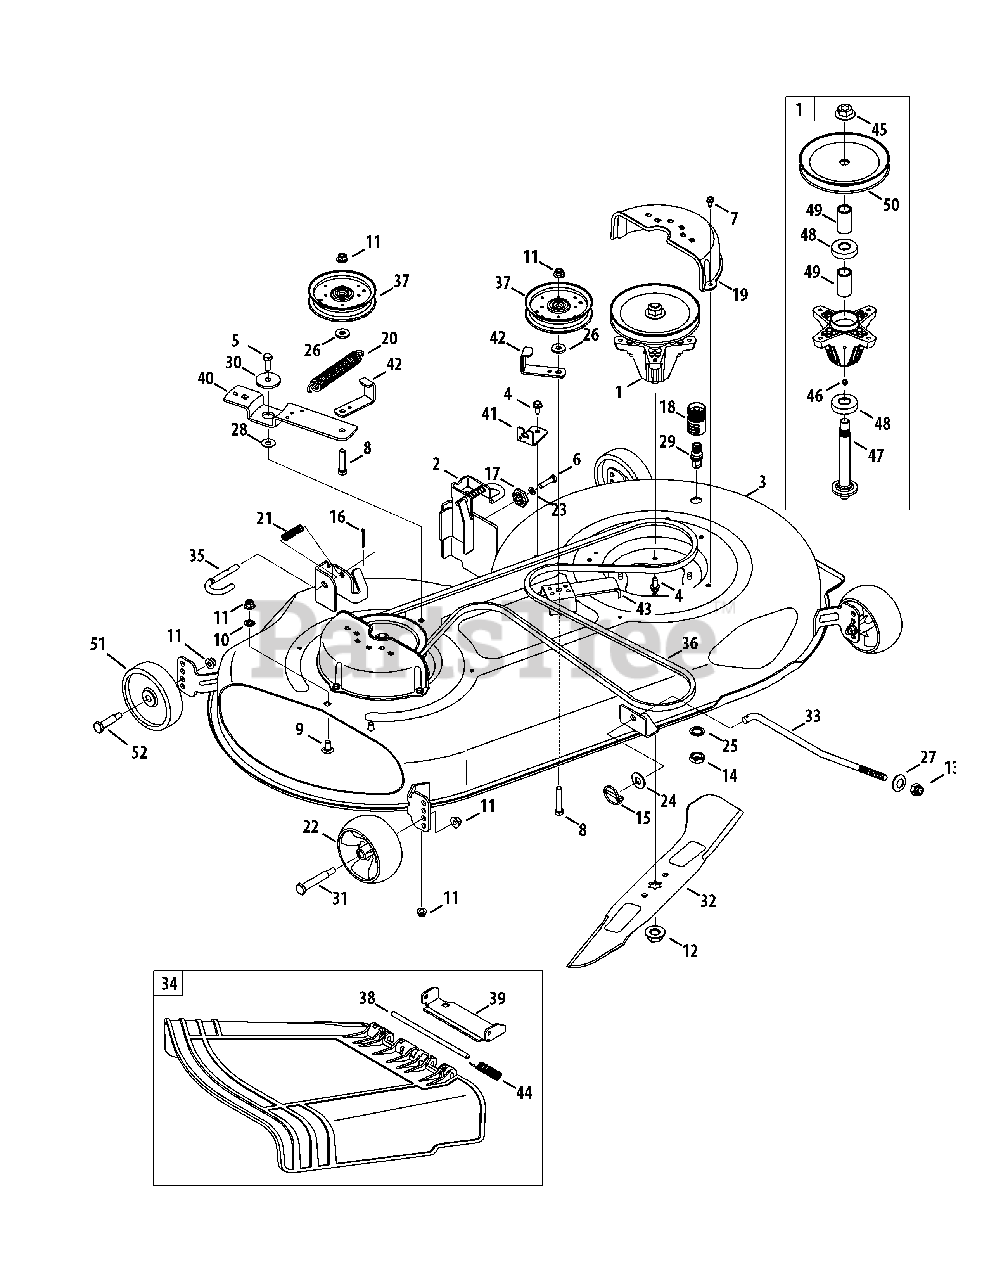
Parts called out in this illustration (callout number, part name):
1	Spindle Assembly, w/Pulley 6.93 Dia.
2	Bracket Assembly, Deck, Hanger LH
3	Deck Assembly, Offset, 46"
4	Screw, Self-tapping, 5/16-18, .750,
5	Hex Screw, 3/8-16, 1.00, Gr5, Std
6	Hex Screw, 5/16-18, 1.25, Gr5, Std
7	Screw, Self-tapping, 1/4-20, 0.500,
8	Hex Screw, 3/8-16, 2.00, Gr5, Std
9	Bolt, Carriage, 3/8-16, 0.75, Gr1
10	Nut, Push, 3/8
11	Nut, Flange Lock, 3/8-16, Nylon
12	Nut, Flange, 5/8-18
13	Nut, 1/2-13
14	Nut, Hex, M16-1.5 Din 936
15	Pin, Lynch, .1875
16	Pin, Cotter, 1/8 X 1.25
17	Gear, Deck, Adj
18	Adapter, Water
19	Cover, Belt, Universal
20	Spring, Extension, .94 Dia. X 6.74
21	Spring, Compression, .535 OD X 1.75
22	Wheel, Deck, 5.0 Dia. Ball
23	Washer, Lock, 5/16, Regular Duty
24	Washer, Flat, .531 X 1.25 X .100
25	Washer, Lock, 5/8, Int. Tooth
26	Washer, Flat, .385 X .870 X .092
27	Washer, Bell, .63 X 1.25 X .18
28	Washer, Flat, .385 X 1.0 X .030
29	Port, Water
30	Spacer, Shoulder, .8840 X .190
31	Bolt, Shoulder, .496 X 2.50, 3/8-16
32	Blade, Cut, 23.25" 2-In-1, Cub
33	Rod, Lift, Deck, Front, 13.7
34	Chute Assembly, 46" Deck
35	Rod, Deck Release .375 Dia.
36	Belt, V-Type, A Sec
37	Pulley, Idler, 4.25" Dia.
38	Pin, Hinge, 7.96
39	Bracket, Chute
40	Bracket, Idler, Pivot
41	Bracket, Cable, Deck Engage
42	Bracket, Guard, Belt, 4.25 Pulley
43	Bracket, Support, Stationary Idler
44	Spring, Torsion, .44 I.D. X 2.0
45	Nut, Flange, 5/8-18
46	Lube Fitting, 3/16
47	Shaft, Spindle, 6.11
48	Bearing, Ball, .787 X 1.85 x.551
49	Spacer, .792 X 1.060 X 1.860
50	Pulley, Deck, 6.93 Dia.
51	Wheel, Deck 5.0 x 1.38
52	Bolt, Shoulder, .496 x 1.525, 3/8-16
